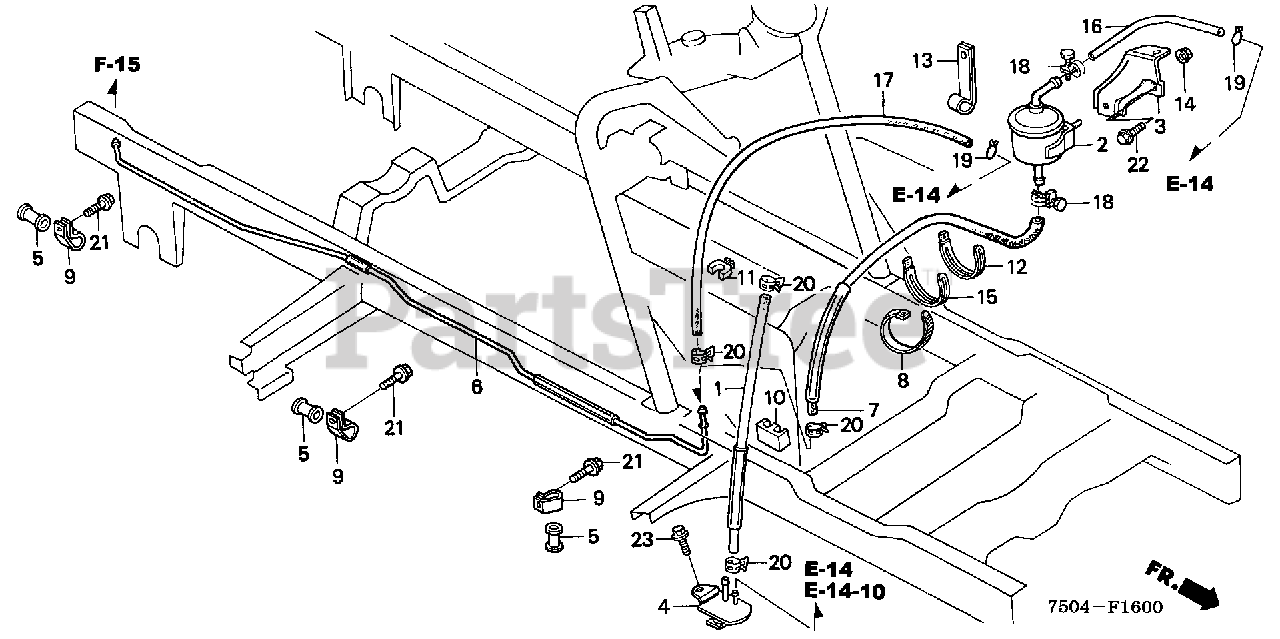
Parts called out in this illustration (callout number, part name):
1	TUBE, FUEL
4	TANK, FUEL CATCH (NOT AVAILABLE)
5	RUBBER, FUEL PIPE INSULATOR
6	PIPE, VENT
8	BAND B1, CABLE
9	CLIP, FUEL PIPE
10	CLIP, DOUBLE
11	CLIP A, FUEL HOSE
13	CLIP B, FUEL HOSE
17	BULK HOSE, FUEL (4.5X3000) (4.5X490)
17	HOSE, FUEL
19	CLIP, TUBE (B8)
20	CLIP, TUBE (D8.5)
21	BOLT, FLANGE (6X12)
23	BOLT, FLANGE (8X16)
